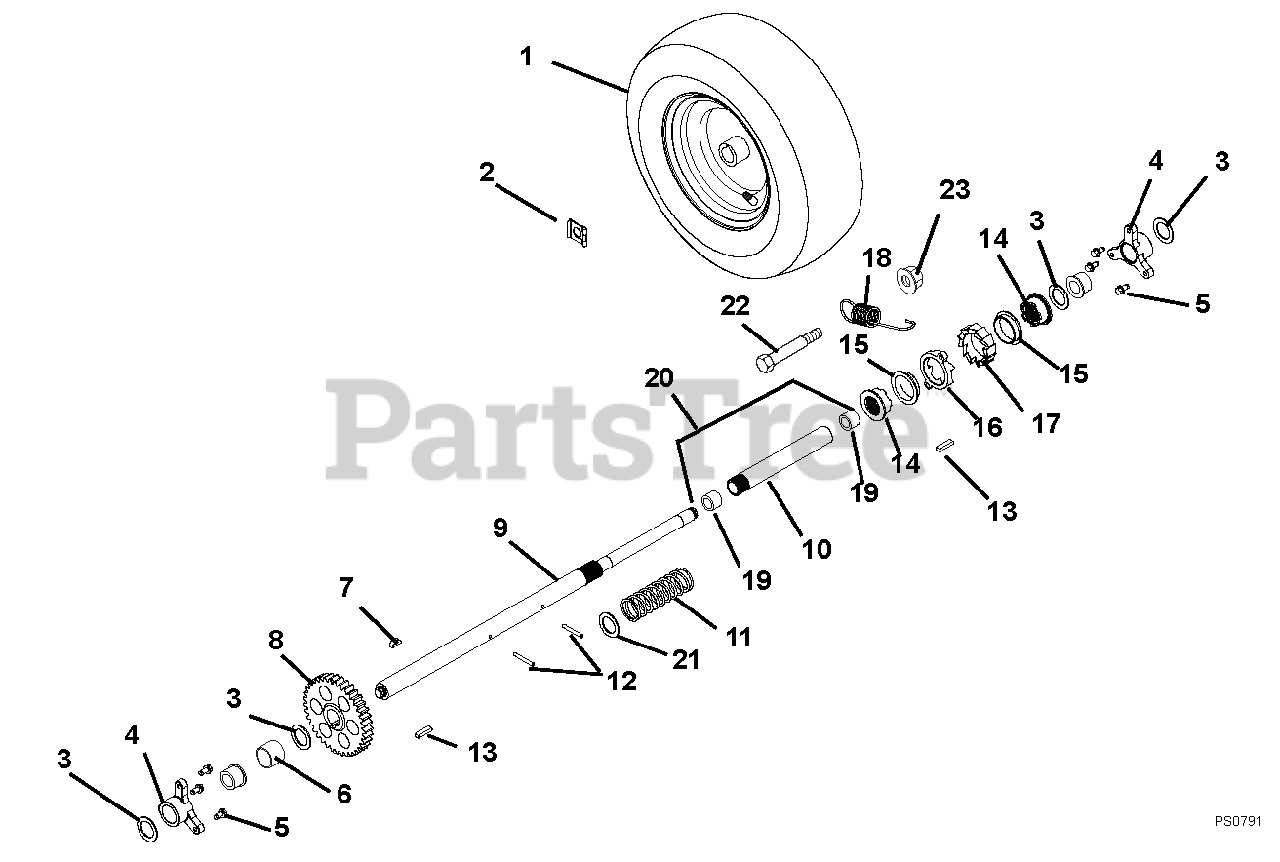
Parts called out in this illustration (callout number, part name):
1	TIRE/WHEEL,RH 15X5.00-6 REMOTE
2	CLIP, SNAP .625 DIA
3	WSHR-FL-STL 1.010X1.505X.062YZ
4	BUSHING, AXLE
5	SCR-TAP .25-20X.50 HWH TR YWZ
6	BSHG-SLV, 1.012X1.125X1.00
7	KEY-WDRF .25X.750X.313 SAE91
8	GEAR, SPUR
9	AXLE, LONG - CLICKER
10	AXLE, SHORT - CLICKER
11	SPRING, COMPRESSION
12	PIN-ROLL .188X1.25
13	KEY-RECT .25X.188X1.00
14	CLUTCH, DOG - SLIDING
15	BUSHING, FLANGE
16	GEAR, CLUTCH
17	GEAR, RATCHET
18	SG-TENS .06X.62X2.94
19	BSHG-SLV .706X.764X.75 BRZ
20	AXLE, CLICKER W/BUSHINGS
21	WSHR-FL-STL 1.010X1.250X.068YZ
22	BLT-SHLDR .50X1.50 .38-16X.625
23	@NUT-LK-TOP-FLG .38-16 YWZC
